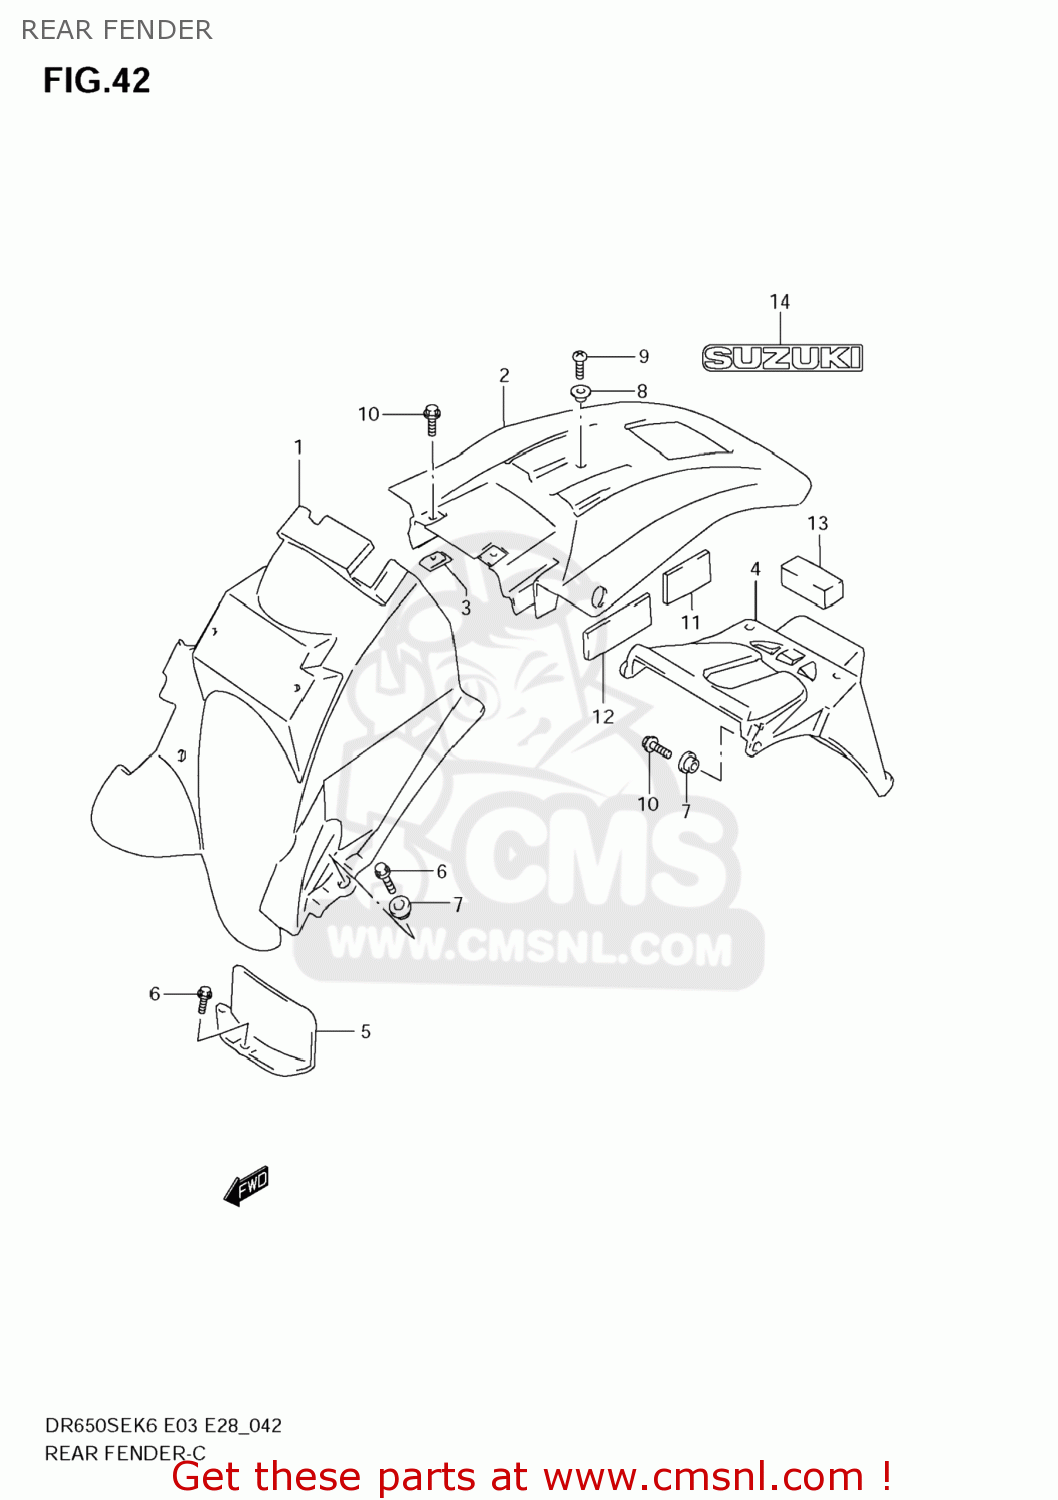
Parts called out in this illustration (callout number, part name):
1	BODY,RR FENDER FR
2	BODY,RR FENDER RR
3	PLATE,FRAME COVER
4	EXTENSION,RR FENDER
5	MUDGUARD,RR FENDER
6	BOLT(6X16)
7	WASHER
8	WASHER
9	SCREW(6X16)
10	BOLT
11	CUSHION
12	CUSHION,RR FENDER
13	CUSHION,EXTENSION
14	EMBLEM,SUZUKI
